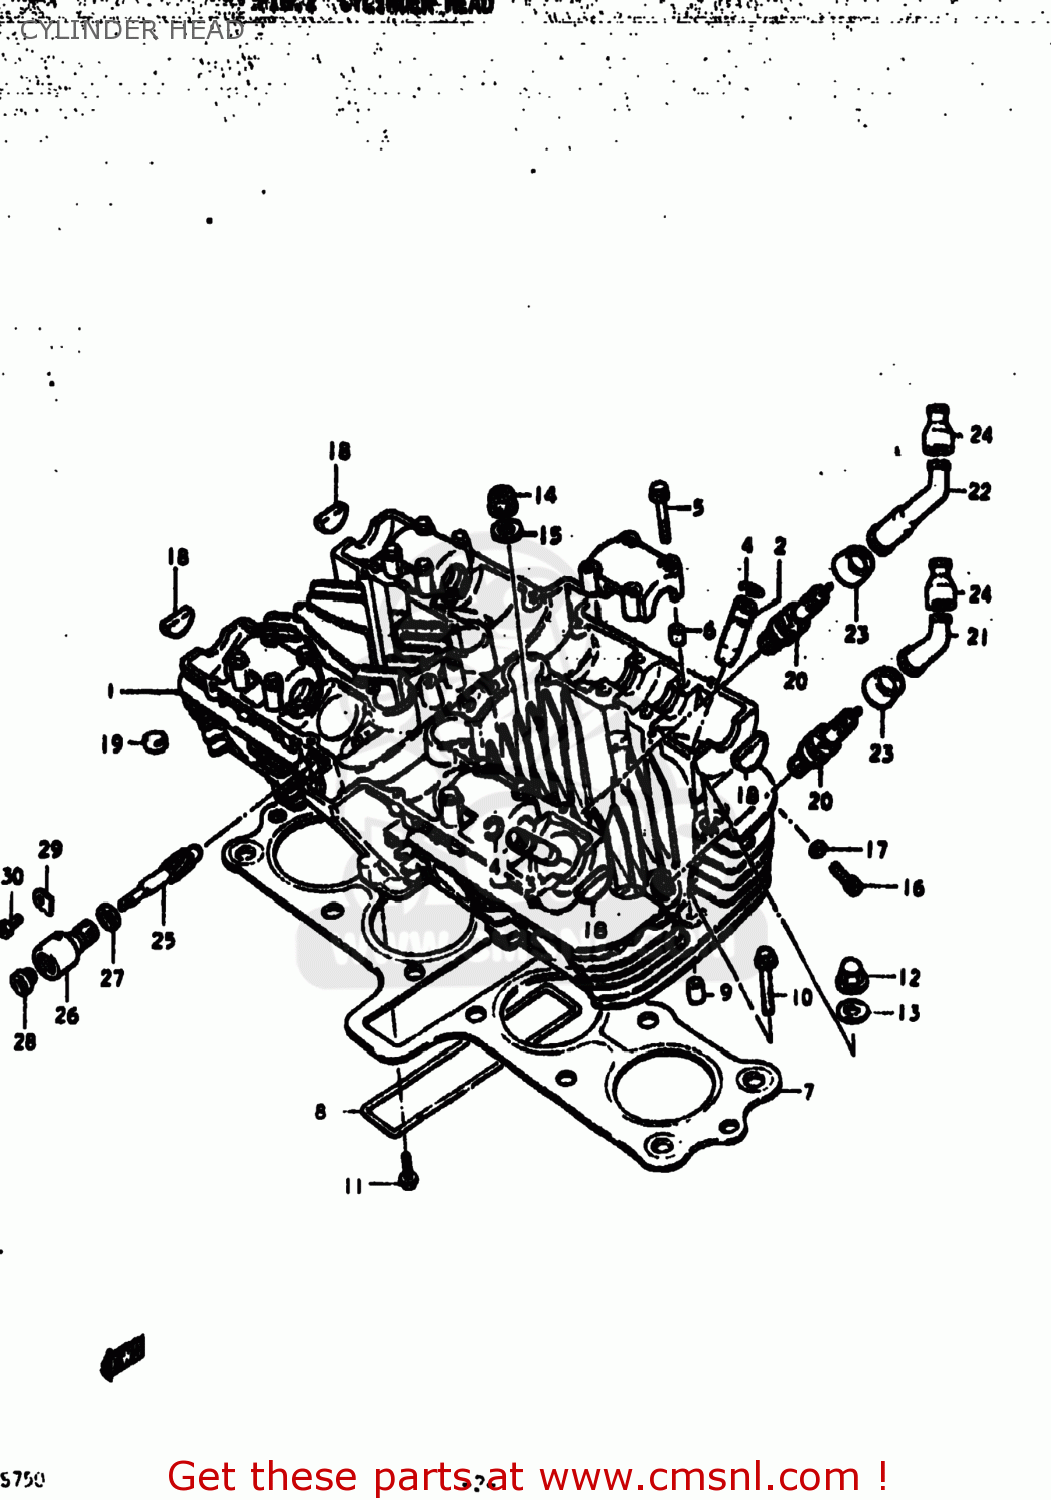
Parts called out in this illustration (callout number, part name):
1	HEAD ASSEMBLY,CYLINDER
2	GUIDE,VALVE
3	GUIDE,VALVE
4	RING,SNAP
5	BOLT(6X39)
6	PIN(6.2X8X11)
7	GASKET,CYLINDER HEAD (MCA)
8	O RING(D:3,ID:26X157)
9	PIN
10	BOLT,UNDER
11	BOLT
12	NUT
13	GASKET(10.5X22X2) (NAS)
14	NUT
15	WASHER(10.5X22X2.3)
16	BOLT
17	GASKET(5.3X9.3X1.2) (NAS)
18	PLUG
19	PAD
20	PLUG,SPARK
21	CAP,SPARK PLUG
22	CAP ASSY,SPARK PLUG
23	SEAL,SPARK PLUG
24	SEAL,SPARK PLU
25	GEAR,TACHOMETER DRIVEN
26	SLEEVE,TACHOMETER DRIVE
27	SEAL,TACHOMETER DRIVEN
28	SEAL
29	PLATE,TACH DRIVE GEAR SLEEVE
30	SCREW(5X12)
